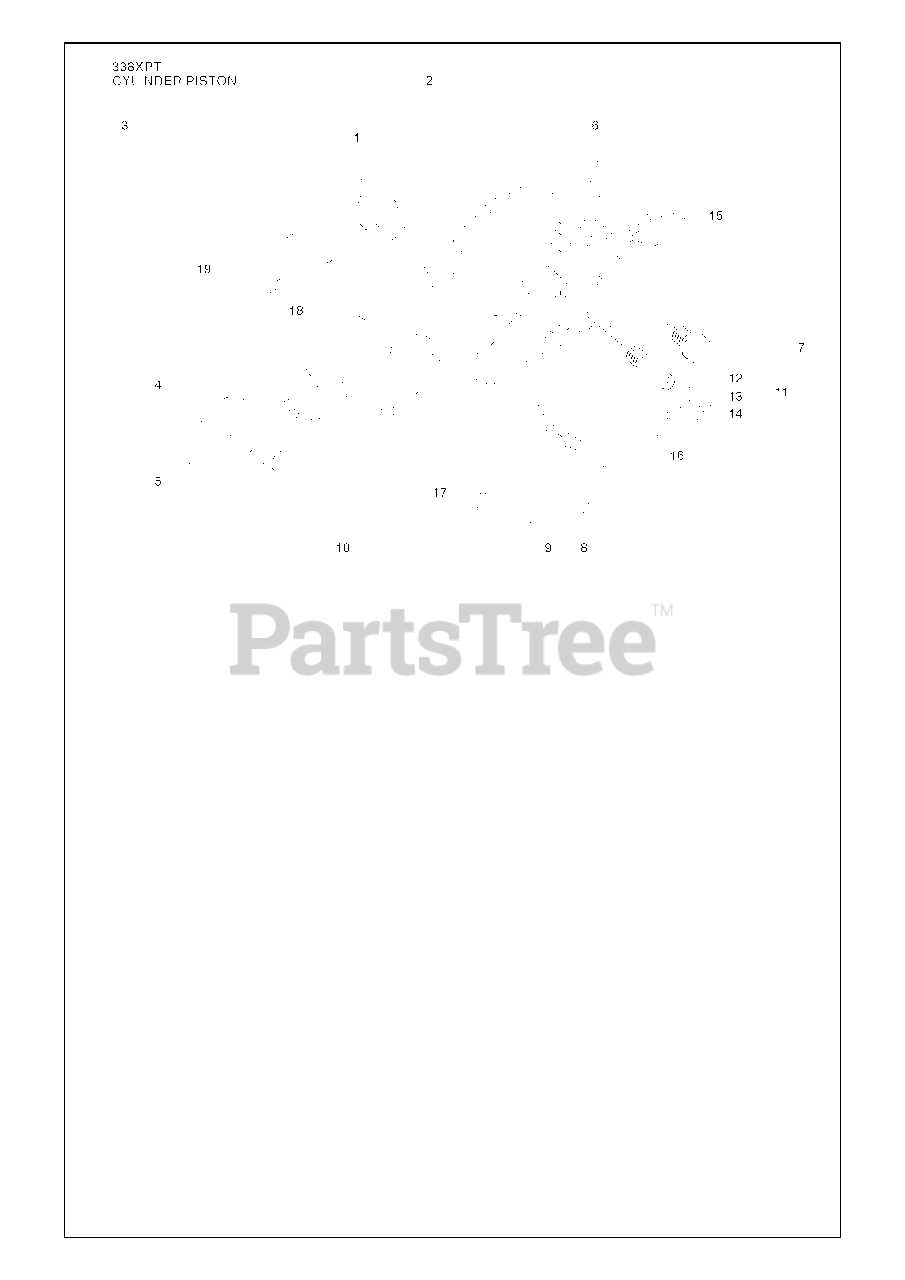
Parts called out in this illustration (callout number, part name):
4	RING
5	LOCKING RING
7	CYLINDER PLUG
8	PROTECTIVE CAP
10	SUPPORT BUSHING
11	VALVE DECOMPR
12	DECOMPRESSION VALVE
15	SPARK PLUG RCJ7Y
16	HOSE ASSY
